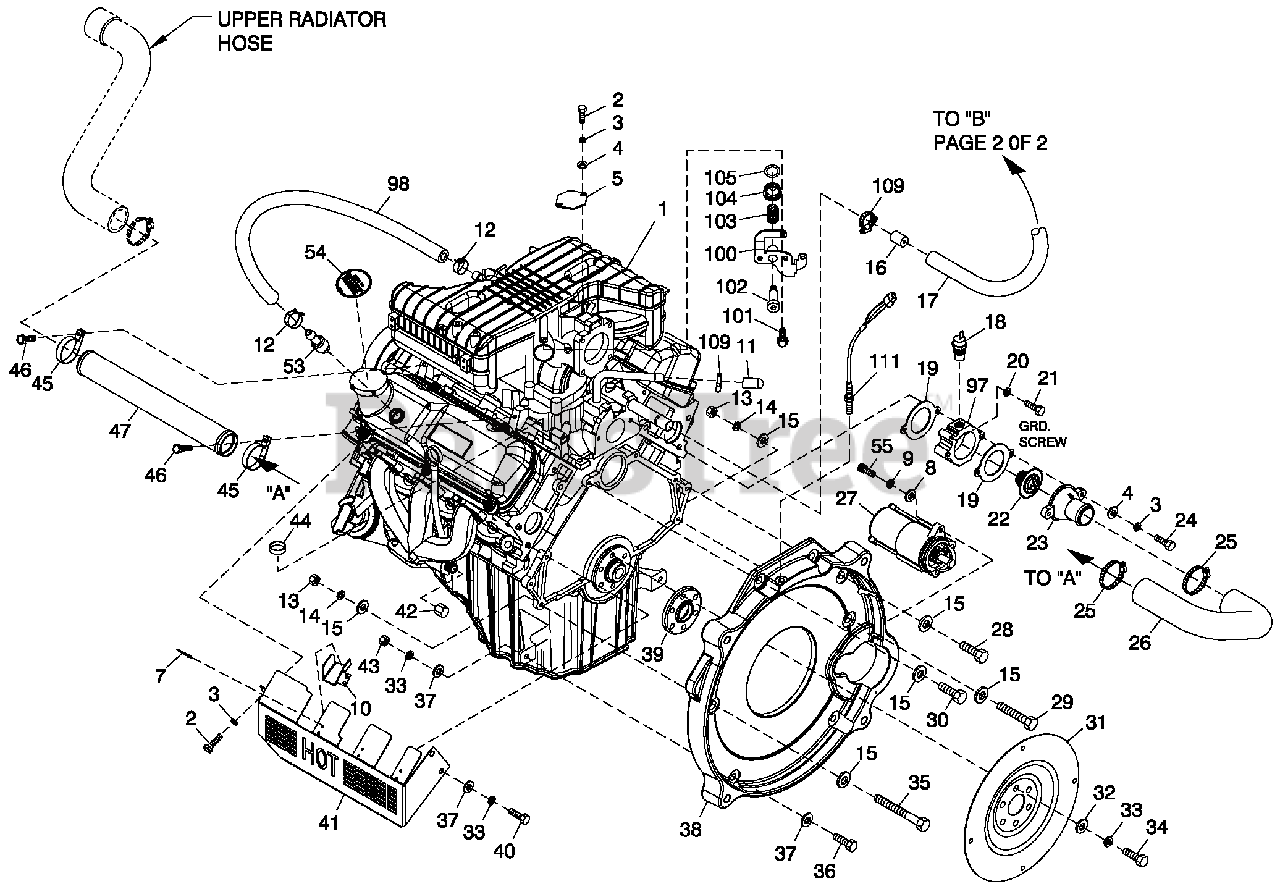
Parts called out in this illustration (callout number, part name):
1	ENGINE 4.2LG3(FWD)
2	SCREW HHC M6-1.0X16C8.8
3	WASHER LOCK M6-1/4
4	WASHER FLAT 1/4-M6 ZINC
5	COVER IAC ACTUATOR
6	SHIELD SPARK PLUG BOOT RH
7	RIVET POP .125X.275SS
8	WASHER FLAT 5/16-M8 ZINC
9	WASHER LOCK M8-5/16
10	SHIELD SPARK PLUG BOOT LH
11	CAP ANTIFREEZE 5/8"ID X 2.5"LG
12	CLAMP HOSE BAND 1.0"
13	NUT HEX M12-1.75 G8YELCHR
14	WASHER LOCK M12
15	WASHER FLAT M12
16	RESTRICTOR COOLANT BYPASS
17	HOSE COOLANT BYPASS 4.2L
18	SWITCH HI-TEMP 245D X 3/8NPT
19	GASKET THERMOSTAT 4.2L
20	WASHER LOCK M5
21	SCREW HHTT M5-0.8X10BP
22	THERMOSTAT 192 DEGREE
23	THERMOSTAT HOUSING
24	SCREW HHC M6-1.0X 60 C8.8
25	CLAMP HOSE #28 1.32-2.25
26	HOSE RADIATOR REAR
27	STARTER MOTOR 12V
28	SCREW HHC M12-1.75 X 30 C8.8
29	SCREW HHC M12-1.75X 60 C10.9
30	SCREW HHC M12-1.75 X 40 C8.8
31	FLEX PLATE G3
32	WASHER FLAT .45X1.00
33	WASHER LOCK M10
34	SCREW HHCM10-1.0X30 C10.9
35	SCREW HHC M12-1.75X 90 C10.9
36	SCREW HHCM10-1.5X35 C8.8
37	WASHER FLAT 3/8-M10 ZINC
38	ENGINE ADAPTER 4.2L MACHINED
39	SPACER FLEXPLATE 4.2L
40	SCREW HHCM10-1.5X20 C8.8
41	HEAT SHIELD EXH 4.2L LH
42	CAP TUBE M22-1.5 STEEL
43	NUT HEX M10-1.5 G8 YEL CHR
44	PLUG EXPANSION 14 OD
45	CLAMP VINYL 1.5 X .281 Z
46	SCREW HHC M6-1.0 X 25 LONG
47	TUBE UPPER COOLANT
48	SCREW HHC M5-0.8X 20 G8.8
49	IGNITION COIL ASSY
50	SCREW HHC M5-0.8X 12 C8.8
52	BRACKET IGNITION COILS G3 4.2L
53	VALVE PCV G3
54	DECAL REFER TO OWNERS MANUAL
55	SCREW SHC M8-1.25 X 30 G12.9
56	WELDMENT IDLER BRACKET 4.2L
57	PULLEY GROOVED ENGINE IDLER
58	BOLT HEX FL HD M8-1.25X 28
59	CAP ANTIFREEZE RUBBER 8.5DIA
60	CLAMP HOSE BAND .75
61	STRAP INTAKE ACTUATOR
62	CAP ANTIFREEZE 5/8"IDX 1.2"LG
63	BRACKET DC ALTERNATOR LH 4.2L
64	ALTERNATOR DC W/OUT PULLEY
65	SPACER ALTERNATOR 4.2L G3
66	CLAMP HOSE BAND .50
67	CAP VINYL 3/8"IDX1"DP BLK
68	SWITCH OIL PRESSURE 10PSI 2P
69	SCREW HHC M8-1.25X 25 C8.8
70	SPACER DC ALTERNATOR PULLEY
71	PULLEY 117 OD DC ALTERNATOR
72	SCREW HHC M10-1.5X 160 C8.8
73	SCREW HHC M8-1.25X 115 LONG
74	SCREW HHC M8-1.25X 105 LONG
75	TUBE COOLANT LOWER RADIATOR
76	O-RING 1-1/2" X 1 -3/4" X 1/8"
77	PULLEY WATER PUMP 4.2L
78	SCREW HHC M6-1.0X12G8.8
79	SPACER 46.5 O.D. X 15 I.D. X 5 THK.
80	SCREW HHC M14-1.5X 40 LONG GRADE 10.9
81	BELT SERPENTINE 71.04"
82	HARMONIC BALANCER REWORK 4.2L
83	WASHER FLAT M5
84	SCREW HHC M5-0.8X 10 C8.8
85	BRACKET DC ALTERNATOR RH 4.2L
86	WASHER NYLON .50 X .87 X .06
87	ADAPTER M12-1.75 X 3/8NPT
88	BARBED STR 3/8NPTX 3/8
89	CLAMP HOSE .38-.87
90	HOSE OIL DRAIN ASSY 21"
91	SCREW HHC M6-1.0X12SS
92	WASHER LOCK 1/4-M6SS
93	WASHER FLAT 1/4 SS
94	HEAT SHIELD EXH 4.2LRH
95	CAP VINYL .5"IDX1.0"DP BLK
96	CLAMP HOSE BAND .63
97	ADAPTER THERMOSTAT
98	HOSE COOL 5/8"ID 250#WP (24" LG)
99	BSHG RDCR HEX 1/4 TO 1/8
100	TUBE ASSY EGR OUTLET REWORK
101	SCREW HHC M6-1.0X 15 LONG
102	BOLT STRIP 3/8-16X1-1/4
103	SPRING COMPRESSION .711 X 1.00
104	PRESSURE RELIEF VALVE
105	O-RING 29mm I.D. X 36mm O.D. X 3.5mm
106	SPARK PLUG WIRE SET 4.2L
107	RETAINER SPARK PLUG WIRE - LOOSE TYPE
108	RETAINER SPARK PLUG WIRE - ATTACHED TYPE
109	CLAMP HOSE#10.56-1.06
110	HARN LOW OIL PRESSURE SWITCH
111	ASSY MAGPICKUP(3/8-24 MALE)
